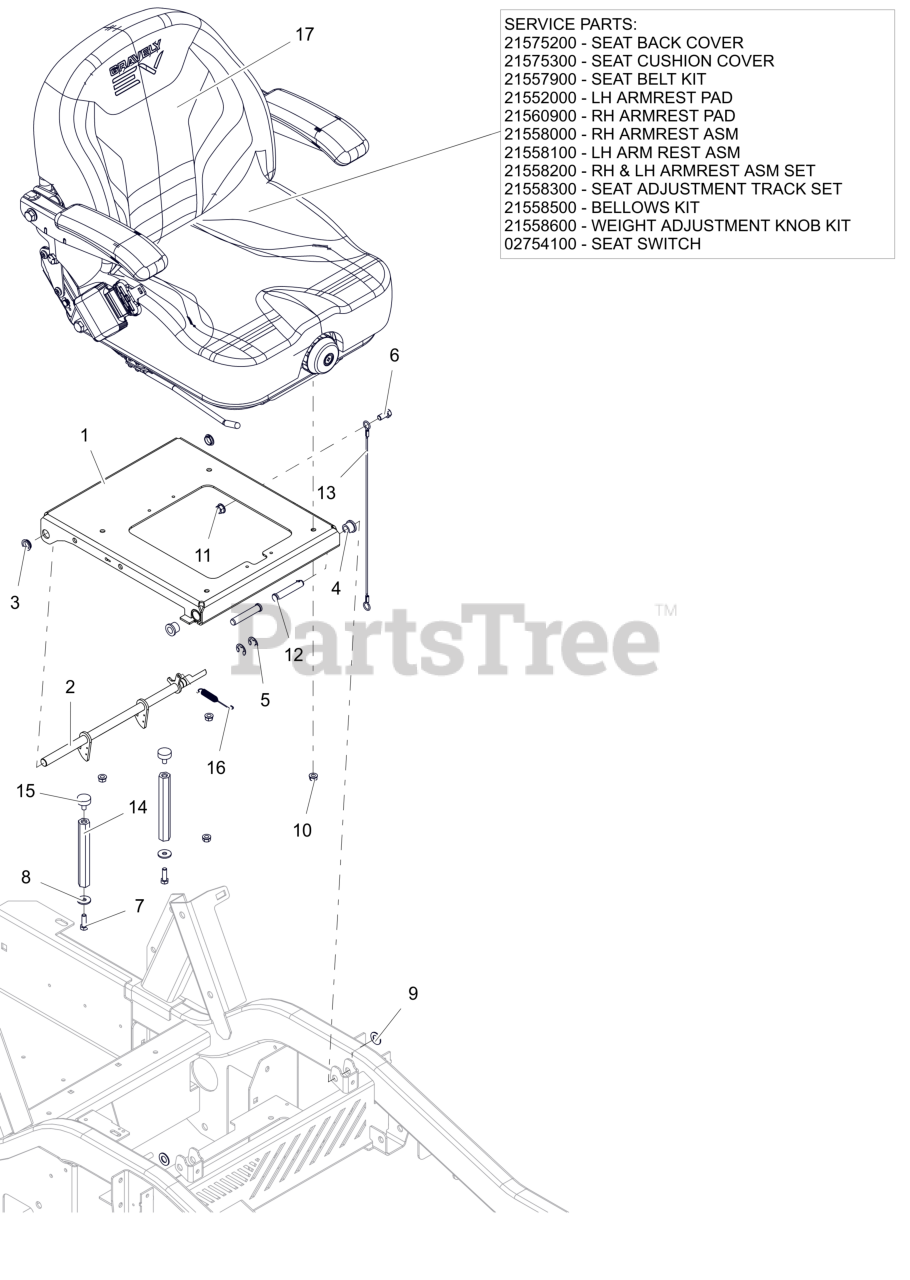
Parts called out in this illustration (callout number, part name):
1	WLDMT, SEAT PLATE (ORANGE)
2	WLDMT, SEAT LATCH (ORANGE)
3	BUSHING, POLYLINER-.63 SNAPIN
4	BSHG, FLG .516X.750X.625X.937
5	RG-RTNG-EXT .625X.042
6	BLT,HEX .38-16X.75 G5 ZCC
7	BLT, HEX .31-18X1.00 G8 ZCC M
8	WSHR,FLT .328X1.00X.094 ZCC
9	WSHR, FLT .531X1.00X.063 ZCC
10	NUT,LK-CTR-FLG .31-18 GF ZCC
11	NUT-LK-CTR-FLG .375-16 GF ZCC
12	PIN-CLIC .50X2.70X2.31 -ZCC
13	CABLE, WIRE (LANYARD)-.093X16.20
14	NUT, COUPLING .312-18 X 5.715
15	BUMPER, RUBBER
16	SG-TENS .043X.44X3.31 WLD 5.8
17	SEAT, GRAVELY MECH SUSPENSION LVR
17	SEAT BACK COVER-BLK/RED
17	SEAT CUSHION COVER
17	SEAT BELT KIT
17	PAD, ARMREST
17	PAD, ARMREST (HARD)
17	RH ARMREST ASM
17	LH ARMREST ASM
17	RH & LH ARMREST ASM SET
17	SEAT ADJUSTMENT
17	BELLOWS KIT
17	WEIGHT ADJUSTMENT KNOB KIT
17	SWITCH- SNAP MTG N.O.
